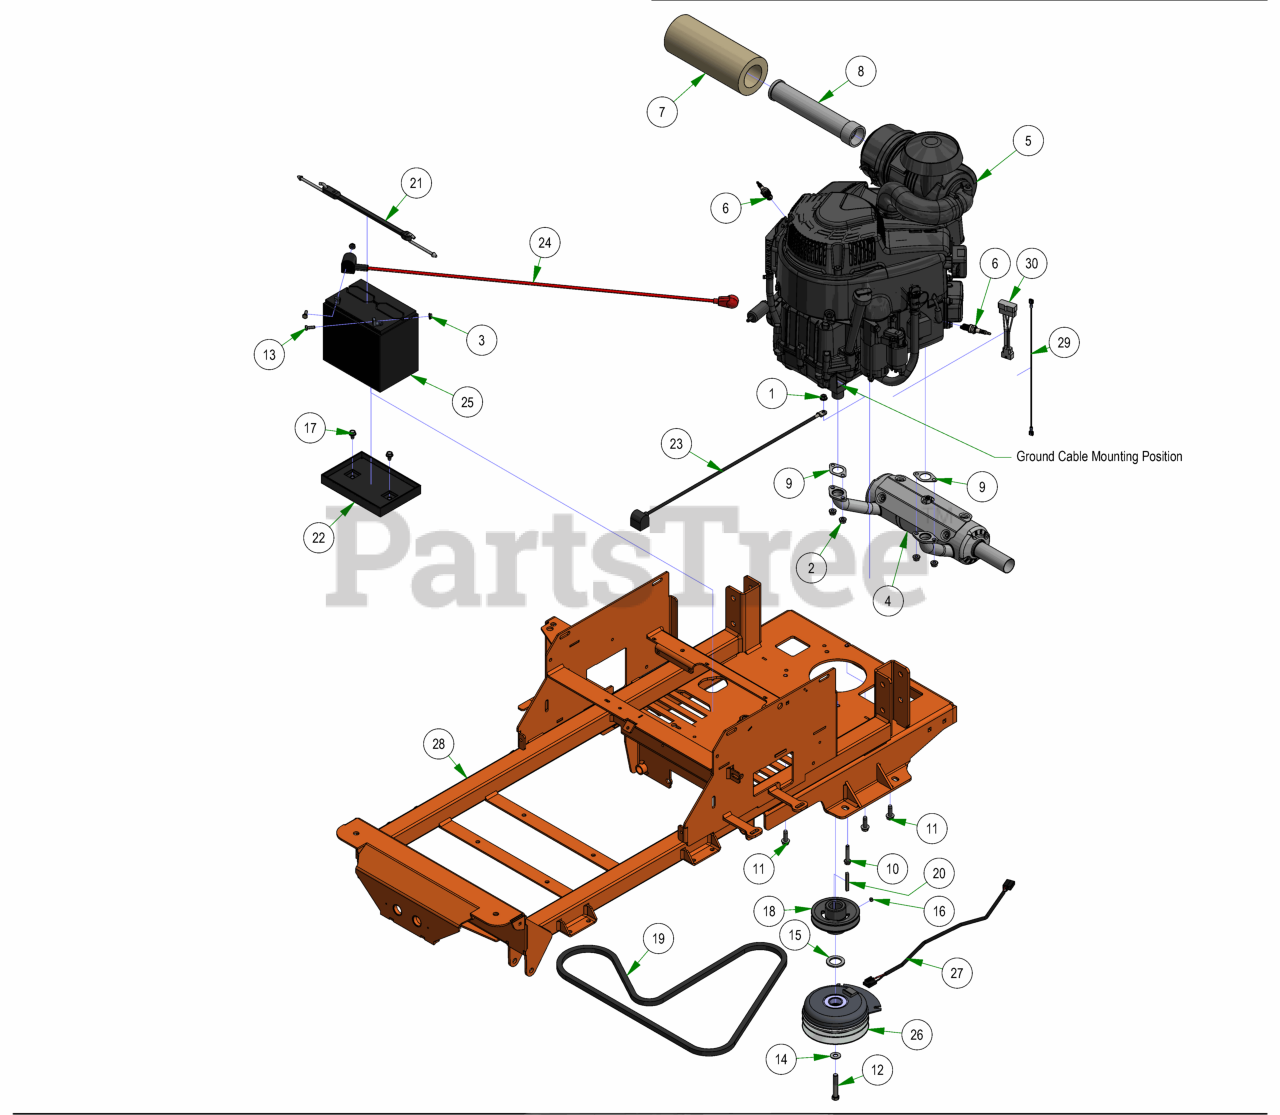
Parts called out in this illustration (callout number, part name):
1	5/16-18 Gr5 Distorted-Thread Flange Locknut
2	Muffler Nut for 015-0511-00 Briggs
3	1/4-20 HEX SERRATED FLANGE NUT HARD/ZINC
4	Maverick HD 28 EFI Muffler
5	28HP Briggs Vanguard 810cc
6	Spark Plug
7	Canister Air Filter- Outer
8	Canister Air Filter- Inner
9	Exhaust Gasket
10	5/16-18x1-3/4 Gr5 Hex Flange Screw Zinc Clear
11	3/8-16 X 1-1/8HEX WASHER UNSLOT SERRATED (TRI-LOB) TRS ZINC
12	7/16-20 X 2.5" HEX Bolt GR.8 W/Patch
13	1/4-20 X 3/4 HEX CAP SCREW (GR.5) ZINC
14	3/8 FLAT WASHER USS (1" OD) ZINC
15	1.140 ID X 1.750 OD X .132 THICK FLAT WASHER PLAIN
16	5/16-24 X 1/4 SOCKET SET SCREW (CUP PT) PLAIN
17	5/16-18 X 1/2 HWH unslot (F) tcs zinc
18	4 3/4 Motor Pulley
19	75.8" Pump Belt
20	1/4 X 2 SQ MACHINERY KEY 1018 STL PLAIN
21	2023 Rubber Battery Hold Down Strap
22	Battery Tray
23	24 inch Black Cable – MZ/ZT
24	36" Red Battery Cable
25	SP-35 Battery
27	Clutch Pigtail
28	2025 Maverick Frame
29	Compact Outlaw/Honda Starter Jumper Wire
30	2021 28 Briggs EFI Pigtail
